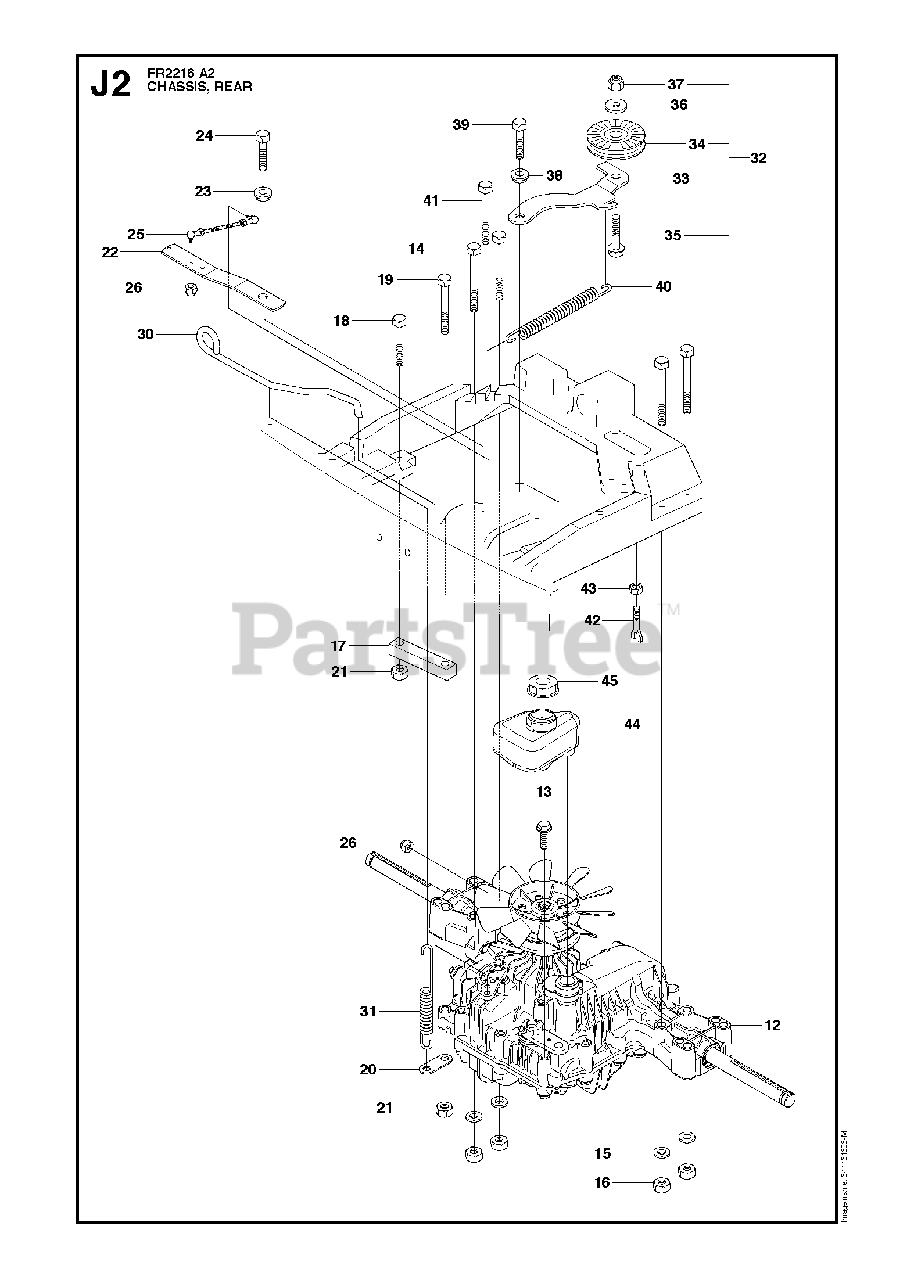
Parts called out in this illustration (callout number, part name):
2	BALL BEARING 6005-2RS
3	BALL BEARING 6010 2RS1
4	CIRCLIP SGH 47
5	RETAINING RING SGA 25
7	RETAINING RING SGA 25
11	BUSHING
12	HYDROSTAT
15	WASHER BRB 8.4X17
16	NUT
20	CONNECTOR
21	NUT
23	WASHER
24	SCREW 8X20
26	LOCKNUT M5
31	SPRING
32	TENSIONER
33	TENSIONER
34	PULLEY
35	SCREW
36	SPACER
37	LOCKNUT M8
38	WASHER
39	SCREW 8X20
46	DRAW RING
